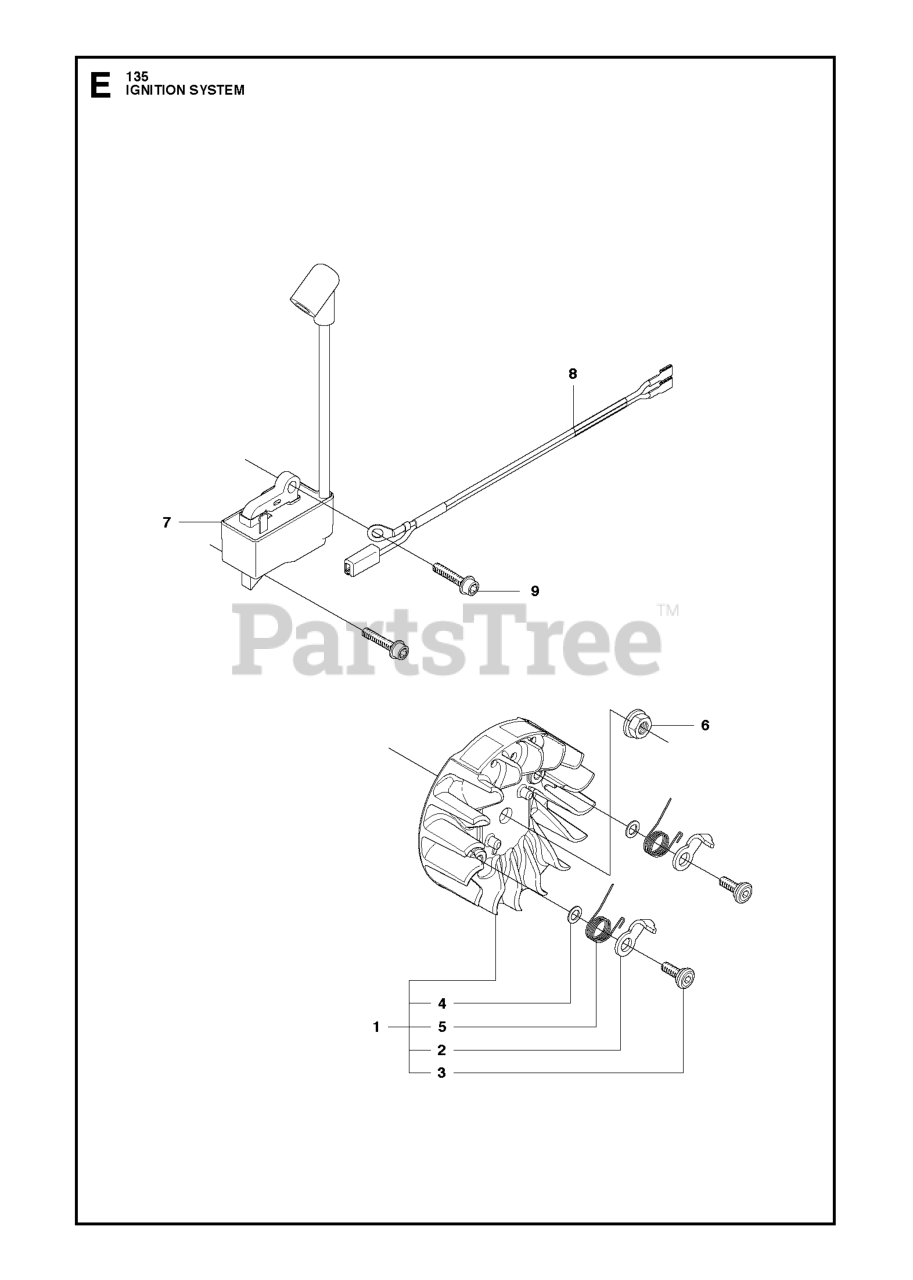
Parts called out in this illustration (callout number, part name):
1	FLYWHEEL ASSY
2	PAWL
3	SCREW
4	WASHER
5	SPRING
6	NUT W/ WASHER
7	IGNITION MODULE
8	WIRING ASSY
9	SCREW
